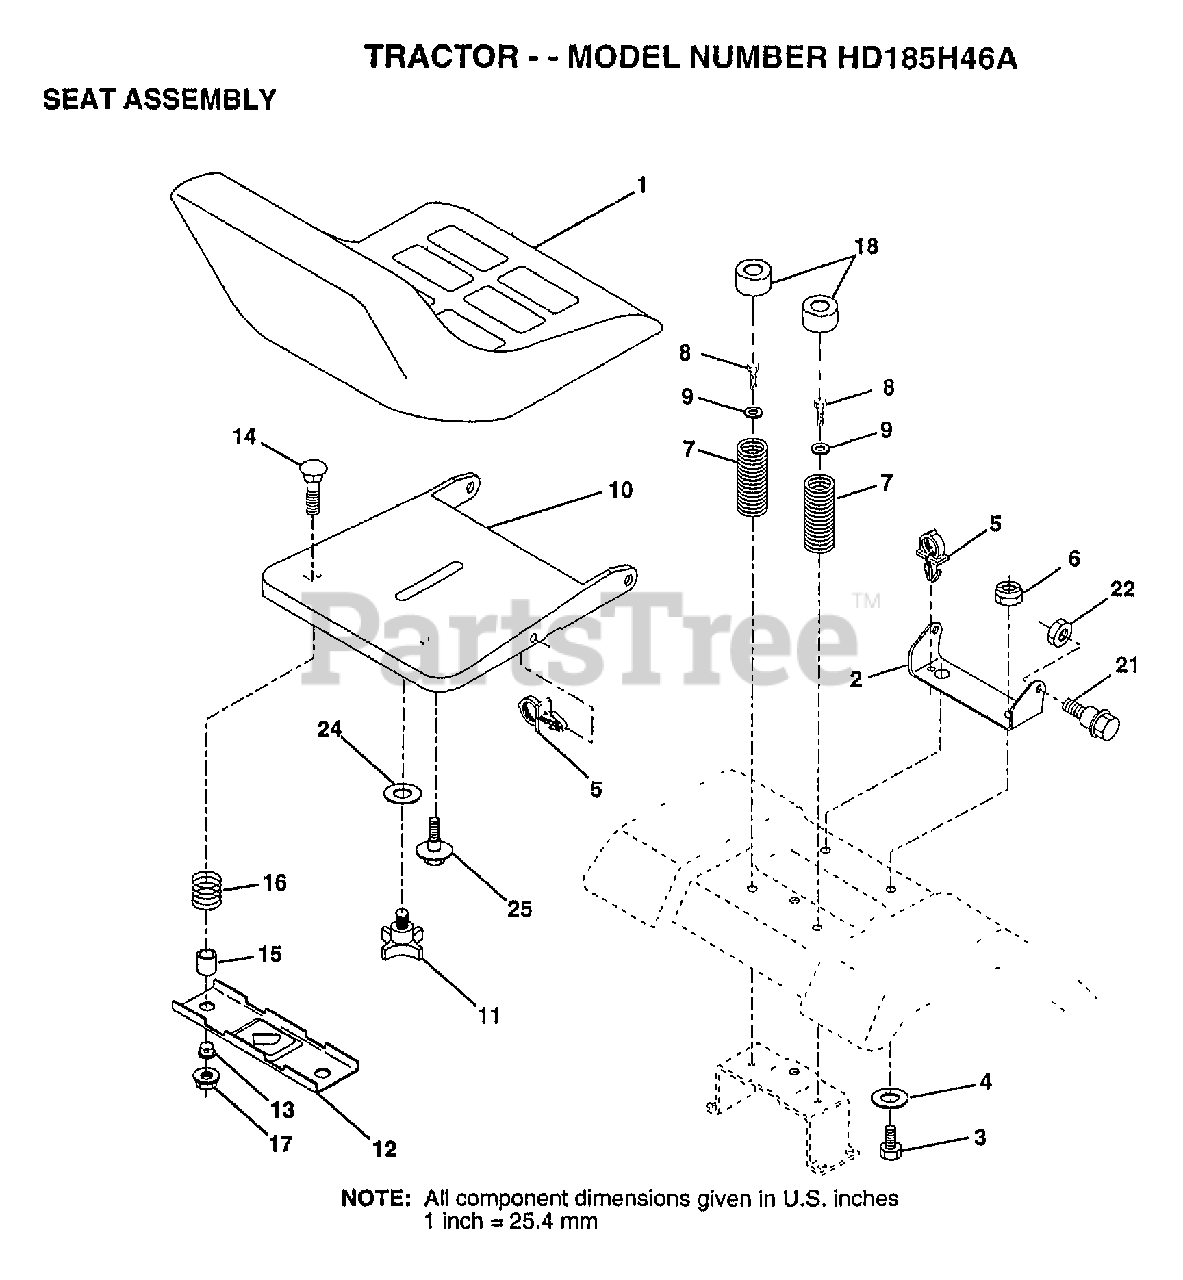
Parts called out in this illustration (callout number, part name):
1	SEAT.2500/1516.BK
2	BRACKET PVT SEAT
5	CLIP.PUSH-IN.HING
6	NUT LOCK HEX W/INS 3/8-16 UNC
7	SPRING COMPRESSIO
10	PAN-SEAT
11	"KNOB 1/2"" YT"
12	BRKT SWITCH
13	BUSHING
15	SPACER SPLIT
16	SPRING COMPRESSED
18	CAP SPRING
21	"BOLT,SHOULDER"
24	WASHER
25	"BOLT,SHOULDER"
27	SCREW LT
28	BOLT.5/16-18.UNC
